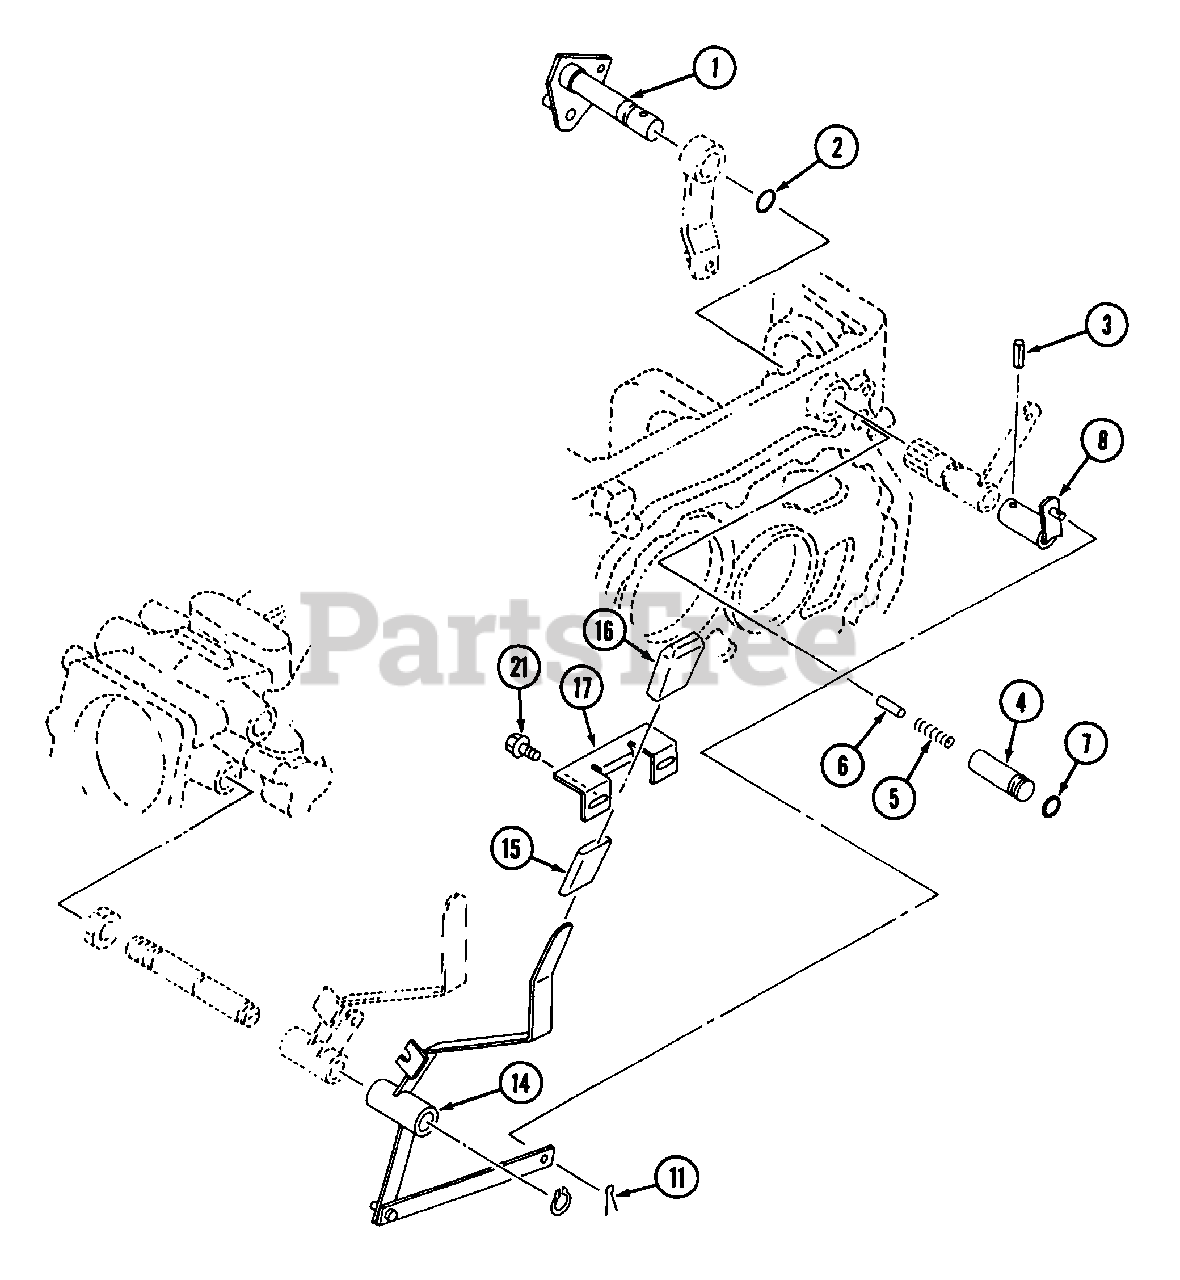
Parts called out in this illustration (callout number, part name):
3	Pin, Spring
11	Pin, Split
14	Lever, Mid PTO
17	Plate, Mid PTO
